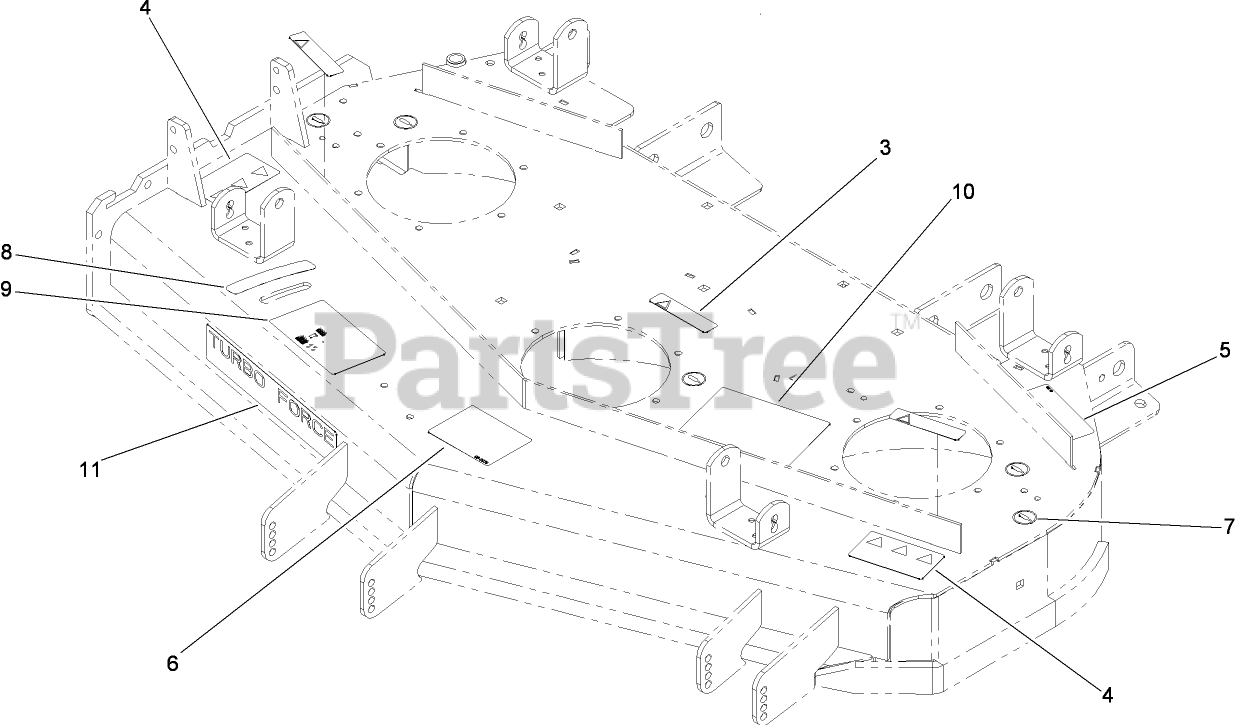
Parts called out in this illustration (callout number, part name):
3	DECAL-WARNING
4	DECAL-DANGER
5	DECAL-TORQUE, BLADE BOLT
6	DECAL-ANTI SCALP
7	DECAL-GREASE
8	DECAL-SETTING, BAFFLE
9	DECAL-ADJUSTMENT, BAFFLE
10	DECAL-SERVICE AID
